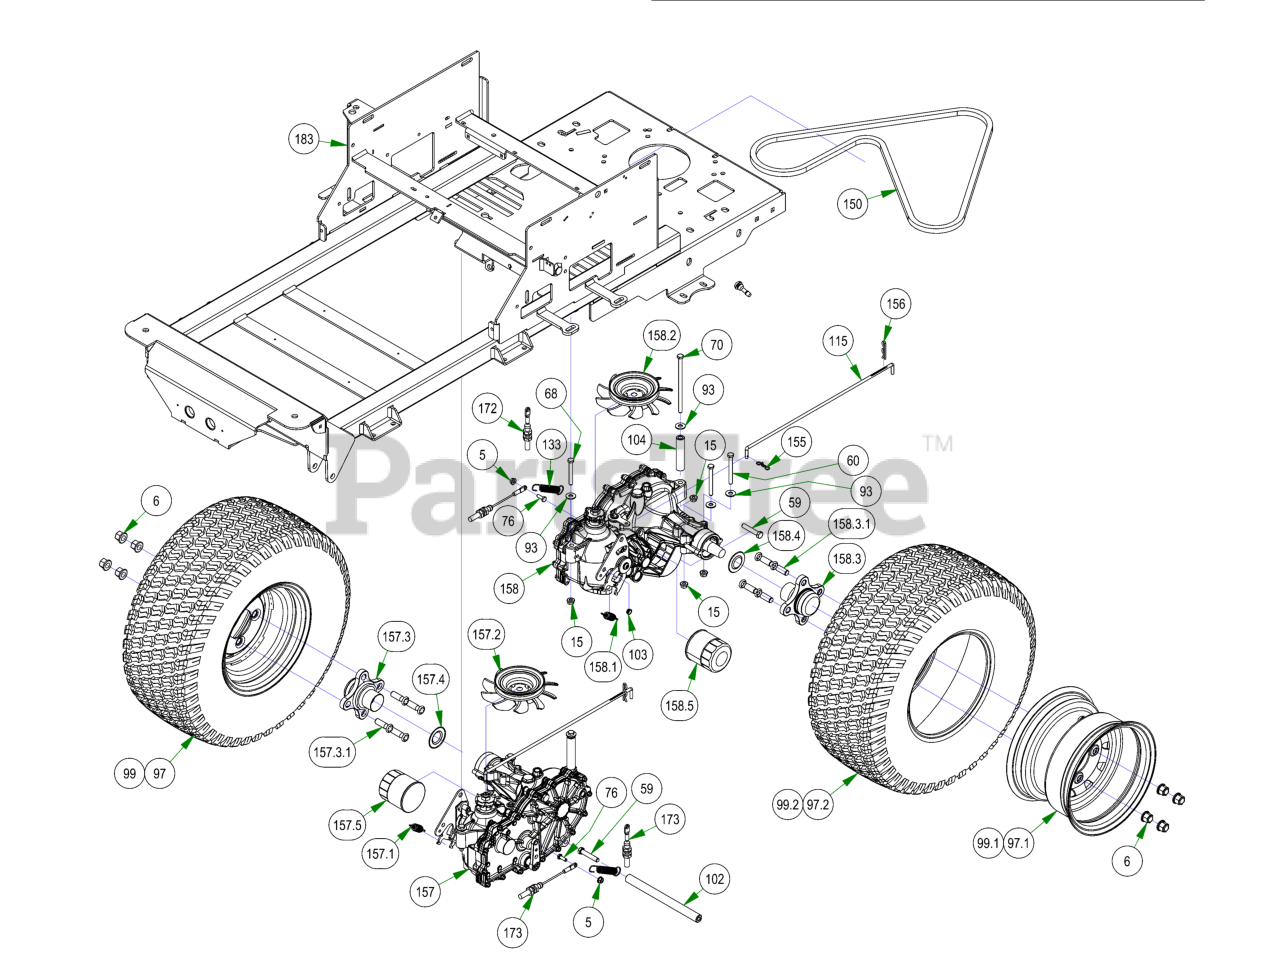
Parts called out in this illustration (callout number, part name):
5	1/4-20 NYL INSERT FLANGE LOCKNUT ZINC
6	Acorn Lug Nut
15	5/16-18 NYLON INSERT FLANGE LOCKNUT ZINC
59	3/8-16 X 2 HEX CAP SCREW (GR.5) ZINC
60	5/16-18 X 3 HEX CAP SCREW (GR.5) ZINC
68	5/16-18 X 2-1/2 HEX CAP SCREW (GR.5) ZINC
70	5/16-18 X 6 HEX CAP SCREW (GR.5) ZINC
76	1/4-20 X 3/4 HEX CAP SCREW (GR.5) ZINC
93	5/16 USS FLAT WASHER (7/8 OD) ZINC
97	ZT Tire and Rim Assembly 22 x 11 - 10
97.1	ZT Wheel Only 22x11-10
97.2	ZT Tire Only 22x11-10
99	2017 ZT Black Assy 22x10-10 48" Deck
99.1	WHEEL, 10", BLACK
99.2	TIRE, 22X10-10
102	2017 Transaxle Spacer-ZT
103	Drive Arm Transaxle Spacer
104	2017 Transaxle Spacer
115	Neutral Rod
133	Brake Return Spring
156	Neutral Rod Clip
157	2021 RH 3100 Transaxle
157.1	Gold Transaxle Spring
157.2	2021 ZT/Maverick Transaxle Fan/Pulley Kit
157.3	ZT Transaxle Wheel Hub
157.3.1	Transaxle Wheel Studs/ Drum Brake Studs
157.4	2021 ZT/Maverick Transaxle Seal Kit (ZT-2800)
157.5	ZT Hydraulic Filter
158	2021 LH 3100 Transaxle
158.1	Gold Transaxle Spring
158.2	2021 ZT/Maverick Transaxle Fan/Pulley Kit
158.3	ZT Transaxle Wheel Hub
158.3.1	Transaxle Wheel Studs/ Drum Brake Studs
158.4	2021 ZT/Maverick Transaxle Seal (ZT-2800)
158.5	ZT Hydraulic Filter
172	2021 Load Balanced Brake Cable 1
173	2021 Load Balanced Brake Cable 2
183	2022 Suspension ZT Frame - Painted
